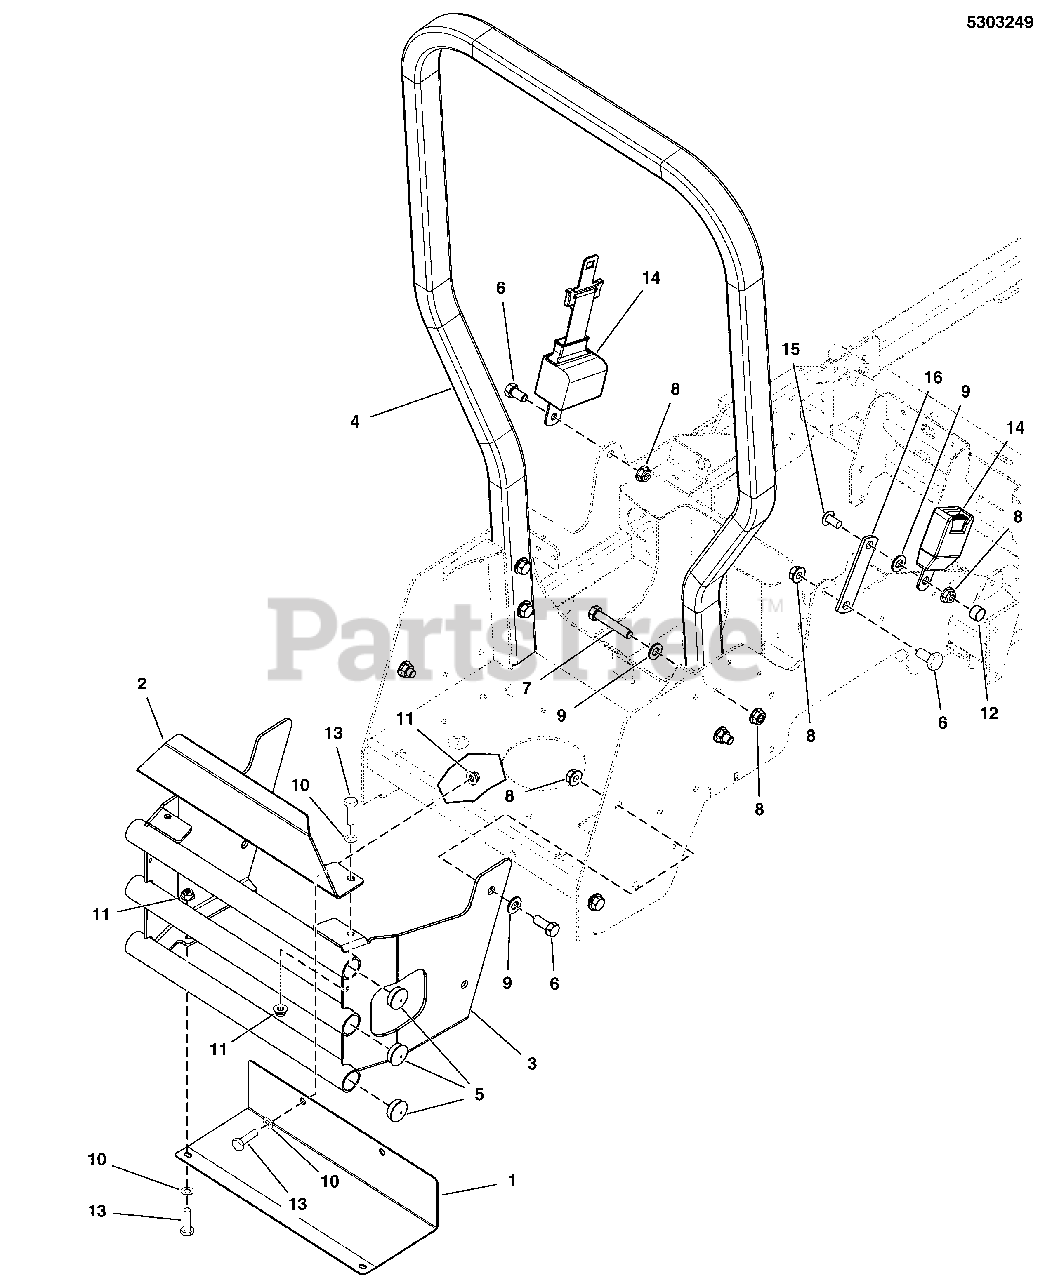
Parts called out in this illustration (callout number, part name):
1	PLATE, HEAT SHIELD - BLK
2	PLATE, CARB PROTECTOR - ORG
3	WELD, BUMPER - IS600 - ORG
4	ROPS (Call 1-800-933-6175 x708 if replacing a ROPS)
5	PLUG, PANEL, 1.25 - BLACK
6	BOLT, 1/2-13 X 1-1/4 GD5 YZ
7	BOLT, 1/2-13 X 2-3/4 GD5 YZ
8	NUT, 1/2-13 HEX NYLOCK FLANGE
9	WASHER, 1/2 SAE
10	WASHER, 5/16 SAE
11	NUT, 5/16-18 HEX NYLOCK FLANGE
12	CAP, VINYL - .750 X .50 - BLK
13	BOLT, 5/16-18 X 1 GD5 YZ
14	SEAT BELT, RETRACTING - ASSM
15	SCREW, 1/2-13 X 1.00, SHCS
16	EXTENSION, SEAT BELT - BLK
